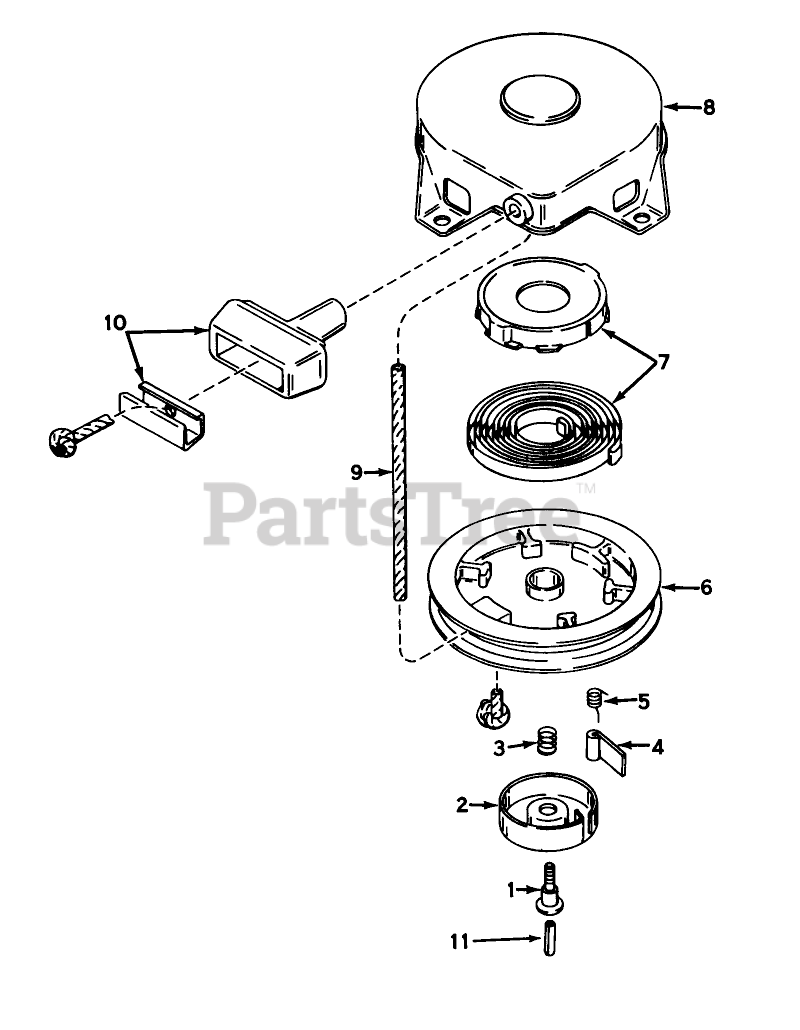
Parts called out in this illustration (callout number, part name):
1	Screw
2	Retainer
3	Spring-Brake
4	Dog-Starter
5	Spring-Dog
6	Pulley
7	Spring Keeper Assy
8	STARTER HOUSING ASSY
9	Rope Starter
10	Assy., Starter
11	Centering
